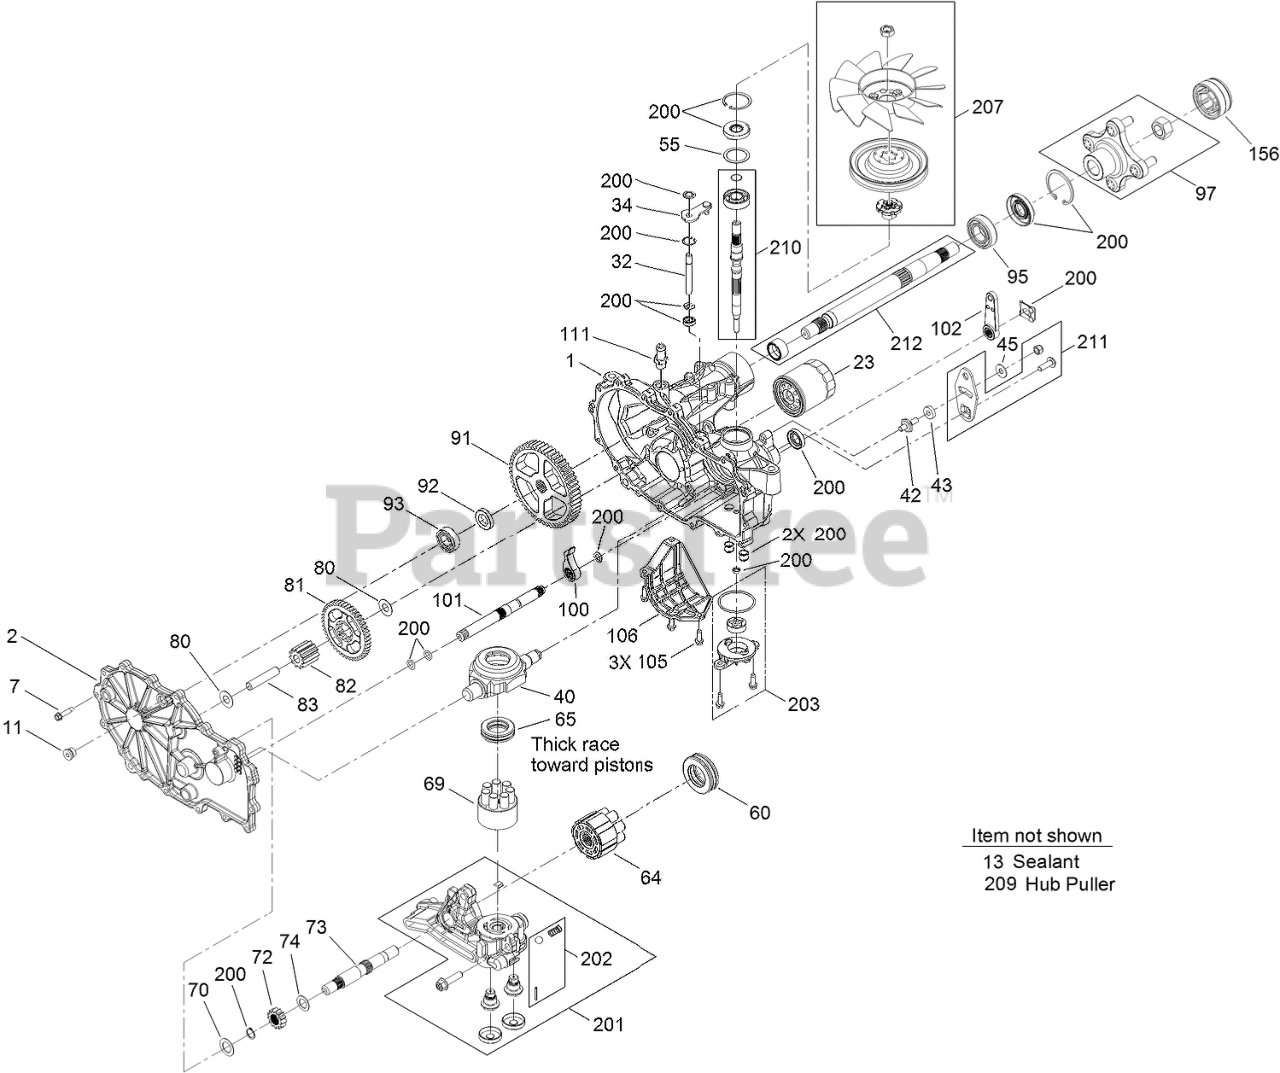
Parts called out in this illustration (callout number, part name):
1	LH MAIN HOUSING KIT
2	LH SIDE COVER KIT
7	SCREW-HHF
11	PLUG-THREAD, STRAIGHT
23	ELEMENT-OIL FILTER, HYD
32	ROD-BYPASS
34	ARM-BYPASS
40	SWASHPLATE-TRUNNION
43	PUCK-FRICTION
45	WASHER
55	SPACER
60	Bearing-Thrust
64	MOTOR CYLINDER BLOCK KIT
65	BEARING-THRUST
69	PUMP BLOCK ASM
70	WASHER-FLAT
72	GEAR-13T
73	SHAFT-MOTOR
74	WASHER
80	WASHER
81	GEAR-46T
82	GEAR-11T
83	PIN-JACKSHAFT
91	GEAR-54T
92	SPACER
93	BEARING-BALL
95	BEARING-BALL
97	HUB KIT
100	PAWL-BRAKE
101	BRAKE SHAFT KIT
102	HANDLE-BRAKE
106	GUARD-FILTER, LH
111	ADAPTER-STRAIGHT
156	COVER-NUT, AXLE
201	LH CENTER SECTION CHARGE KIT
202	CHARGE RELIEF KIT
203	CHARGE KIT
207	FAN AND PULLEY KIT
210	INPUT SHAFT KIT
211	CONTROL ARM KIT
212	AXLE SHAFT KIT
